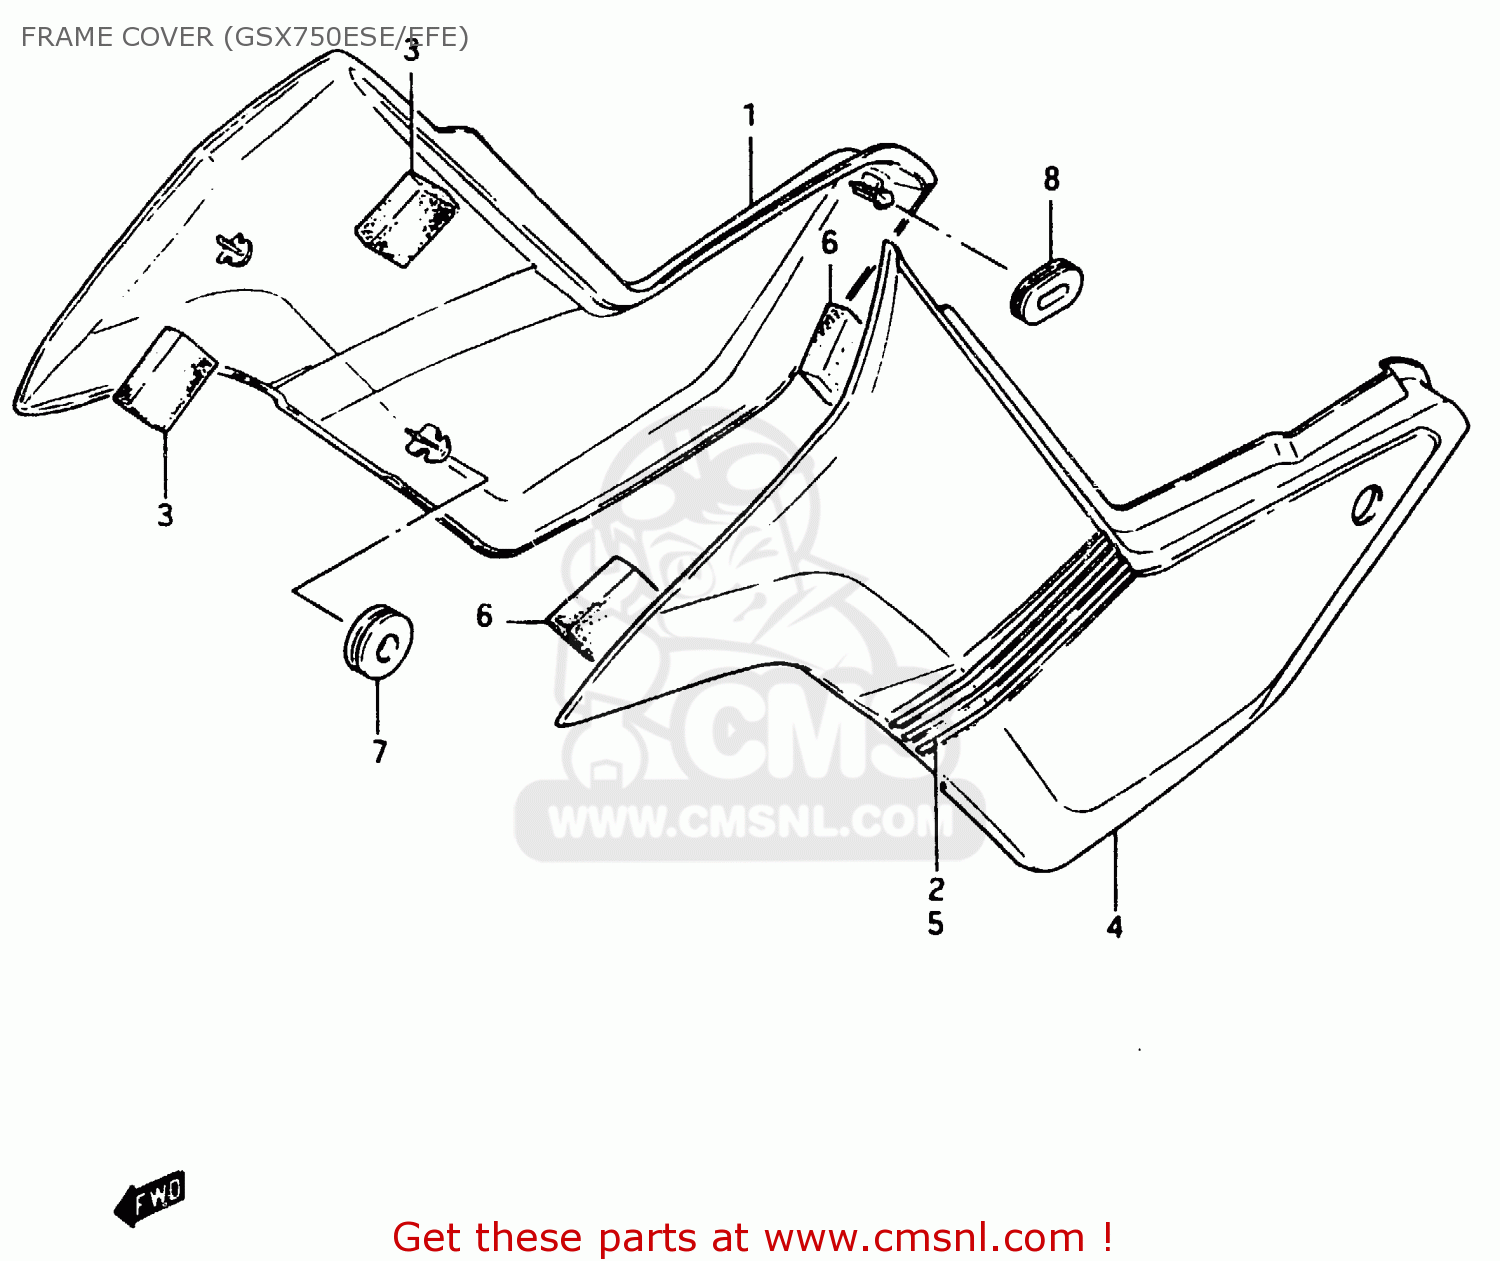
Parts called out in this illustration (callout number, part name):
1	COVER,FRAME RH
2	DENT,FRAME COVER,RIGHT
3	CUSHION
4	COVER, FRAME LH
5	DENT,FRAME COVER,LEFT
6	CUSHION
7	CUSHION
8	CUSHION
